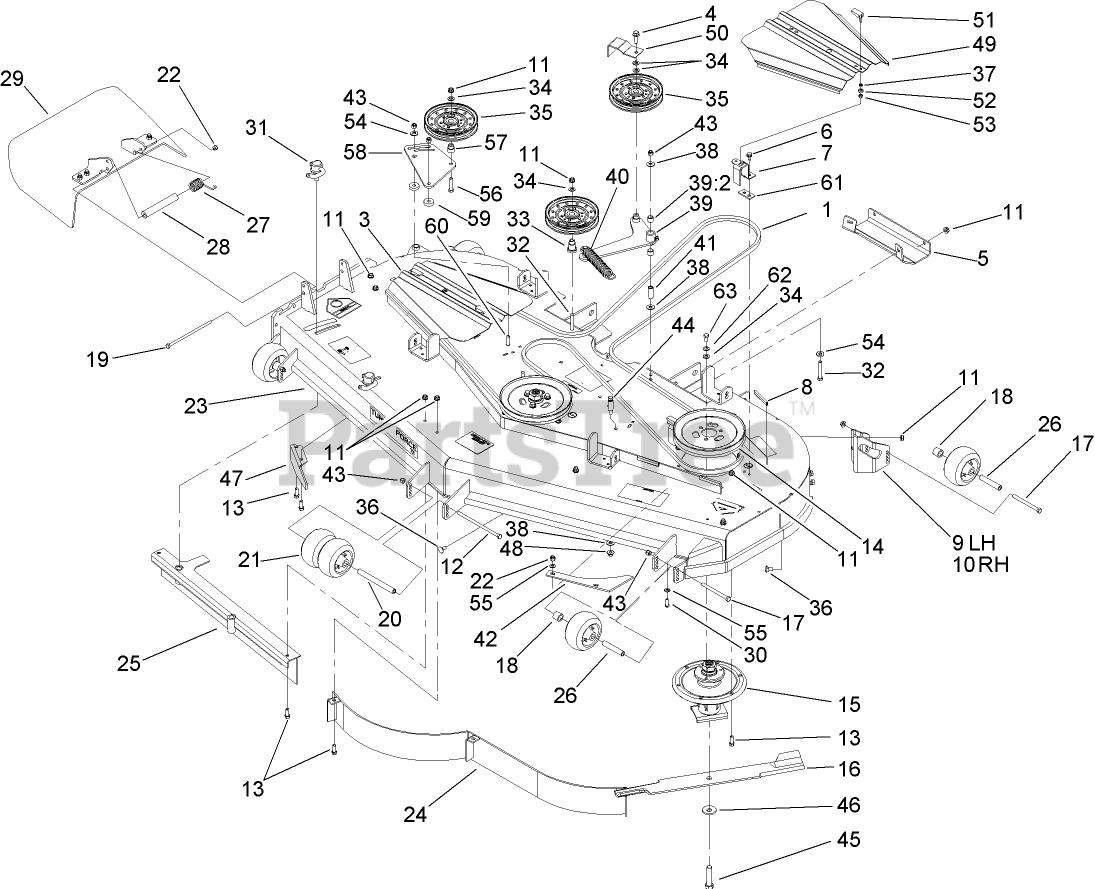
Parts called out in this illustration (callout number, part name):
3	COVER-BELT, RH
4	SCREW-HHF
5	Plate-Skid
6	SCREW-HWHTF
7	BRACKET-COVER
8	STRIP-SEAL
9	MOUNT-WHEEL, LH
10	MOUNT-WHEEL, RH
11	NUT-HHF, WHIZ
12	SCREW-HH
13	SCREW-HWH
14	Pulley
15	SPINDLE ASM
16	BLADE-HI FLOW, 24.5 INCH
17	SCREW-HH
18	TUBE-SPACER
19	SCREW-HH
20	SPACER-WHEEL
21	ROLLER-SCALP, ANTI
22	NUT-LOCK, NI
23	DECK DECAL ASM
26	TUBE-SPANNER
27	SPRING-TORSION
28	SPACER
29	RUBBER DEFLECTOR ASM
30	SCREW-HSBH
31	LEVER ASM
32	SCREW-HH
33	MOUNT-PULLEY
34	WASHER-FLAT
35	Idler-Flat
36	SCREW-CARR
37	WASHER
38	WASHER-FLAT
39	DECK IDLER ARM ASM
39:2	SLEEVE-BEARING
40	SPRING-EXTENSION
41	BUSHING
42	PLATE-TURBO
43	NUT-LOCK, NI
44	PIN-THREADED, SPRING ANCHOR
45	SCREW-BLADE
46	Washer-Blade Bolt, Heavy
47	BAFFLE-DISCHARGE
48	NUT-HF
49	COVER-BELT, LH
50	GUIDE-BELT
51	HANDLE-LATCH, SWELL
52	BUSHING-LATCH, SWELL
53	NUT-LOCK, HH
54	WASHER-BELLEVILLE
55	WASHER-SPRING
56	SCREW-HH
57	BUSHING-IDLER
58	Plate-Idler
59	Spacer
60	SCREW-CARR
61	SPACER-COVER, BELT
62	WASHER-BELLEVILLE
63	SCREW-HH
